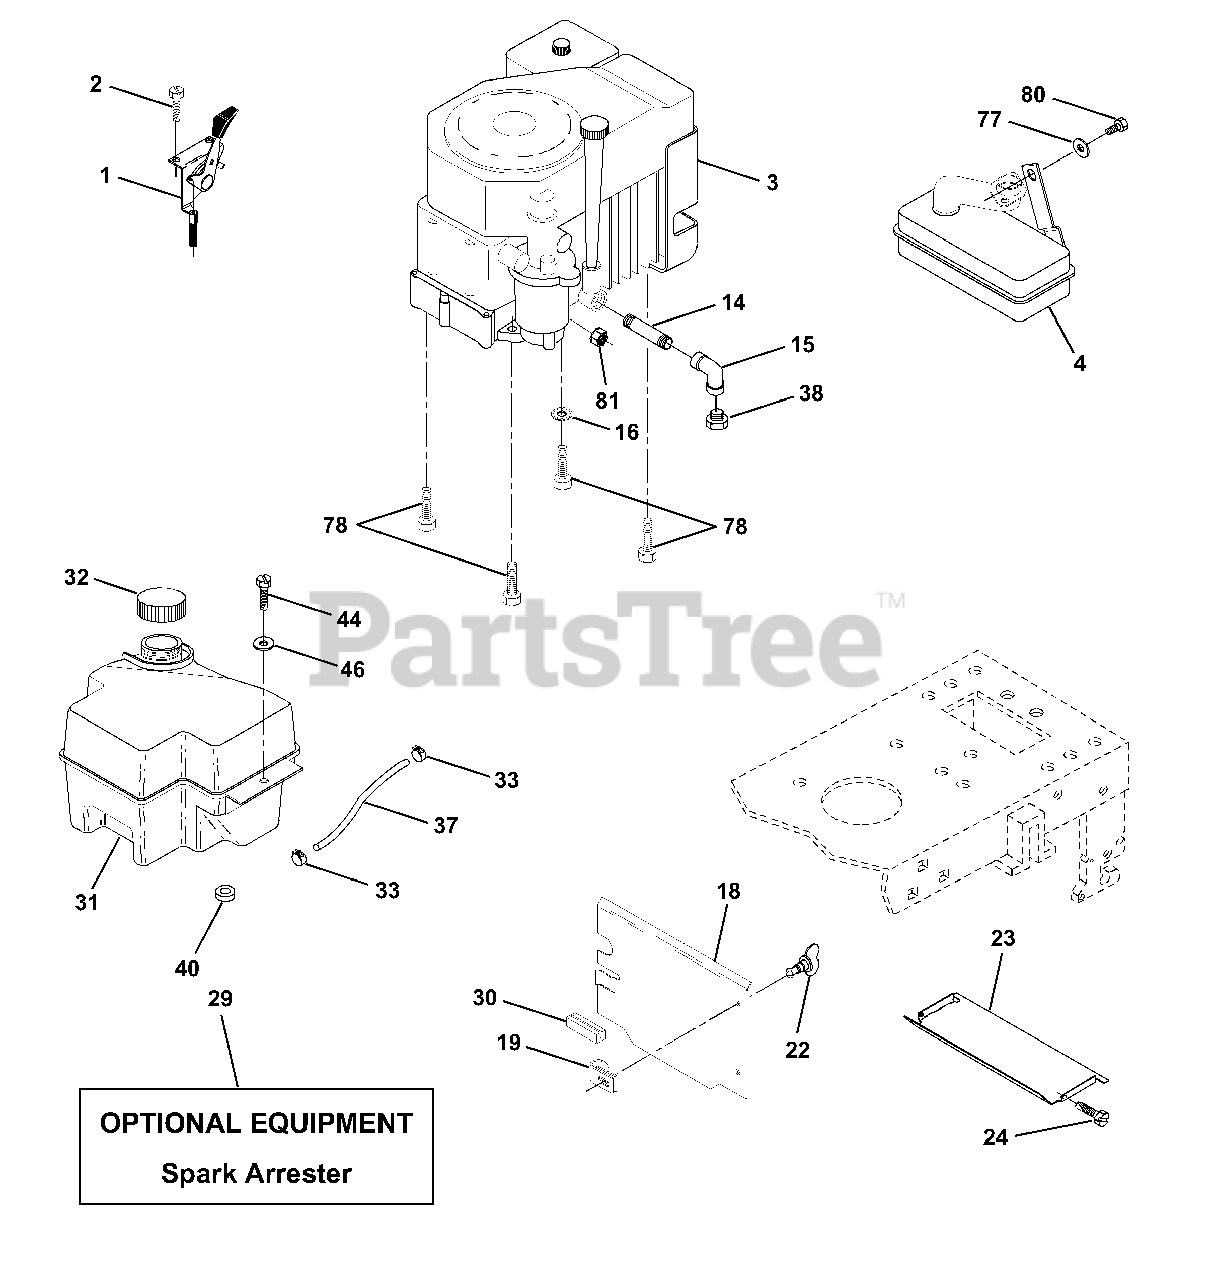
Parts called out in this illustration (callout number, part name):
1	Control THTICH 27 LH FIAG DOM
2	Screw Hex Thd Cut 1/4-20x5/8 T
3	Engine Kohler, Model Number CV15S 13 HP
4	Muffler LT Koh 12.5/15HD
14	Nipple Pipe 3/8 Npt X 3-1/2
15	Elbow Std 90 Degree 3/8-18 Npt
16	Washer Lock Ext Tooth 5/16
18	Shield Heat Lt
19	Receptacle 1/4 turn
20	Retainer 1/4 turn
21	Washer 9/32 x 5/8 x 16 Ga.
22	Stud 1/4 turn
23	Shield Heat Browning LT/YT
24	Screw Tap Hex #10-24unc X 1/2
29	Kit Spark Arrestor (Flat Scrn)
30	Pinch Weld Hood Black
31	Tank Fuel Front 2 00
32	Cap Asm Fuel W/sym Vented
33	Clamp Hose Black
37	Line Fuel 20"
38	Plug Oil Drain
40	Bushing Snap Nyl Blk Fuel Line
44	Screw Hexwsh Thdrol 1/4-20x3/4
46	Washer 9/32 X 7/8 X 16 Ga
77	Washer 5/16 x 3/4 x 16 Ga.
78	Bolt, Engine Mounting
80	Bolt Hex Hd 5/16-18 UNC x 1/2
81	Nut Flange 1/4-20 Starter Nut
